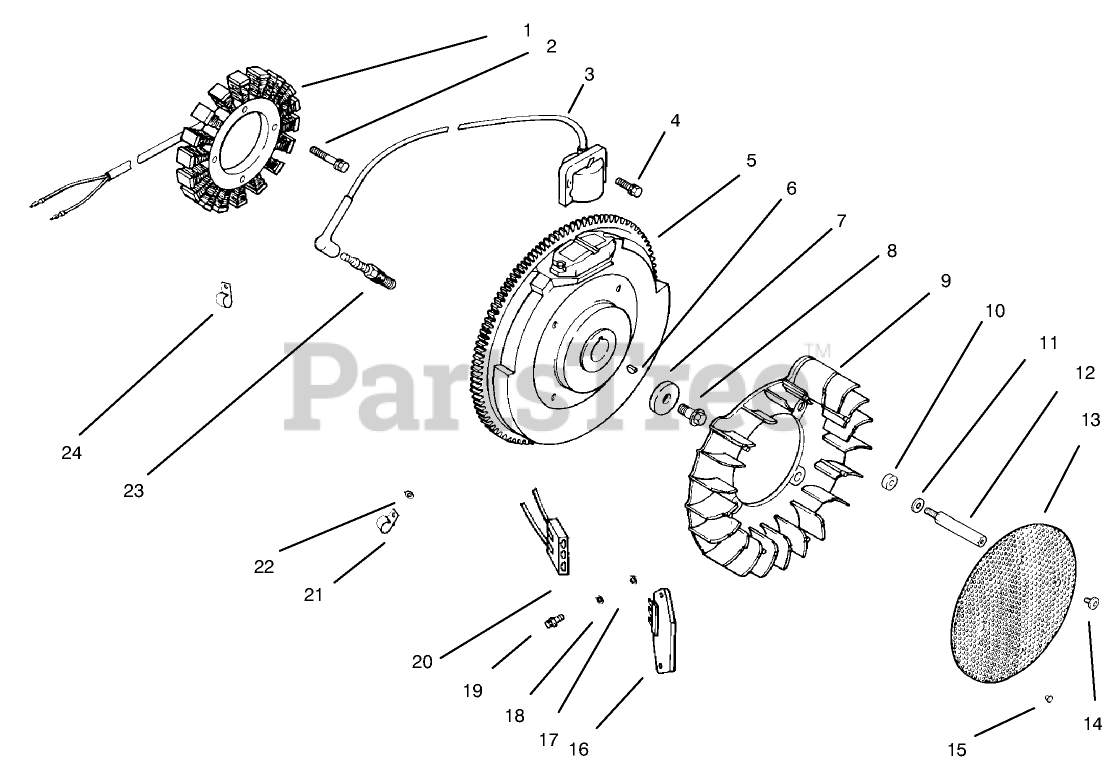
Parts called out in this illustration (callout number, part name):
1	Stator-15 Amp
1	Muffler
2	Screw
2	Stud
3	Module-Ignition
3	Gaskt-Exhaust
4	Screw
4	Nut
5	Flywheel
5	Screw, tank bracket - starter end
6	Key
7	Washer
8	Screw
9	Fan
10	Spacer
11	Washer
12	Stud
13	Screen-Grass
14	Screw
15	Screw-Set
16	Rectifier-Regulator
17	Washer
18	Washer
19	Screw
20	Connector
21	Clip
22	Washer
23	Plug-Spark
24	Clip
